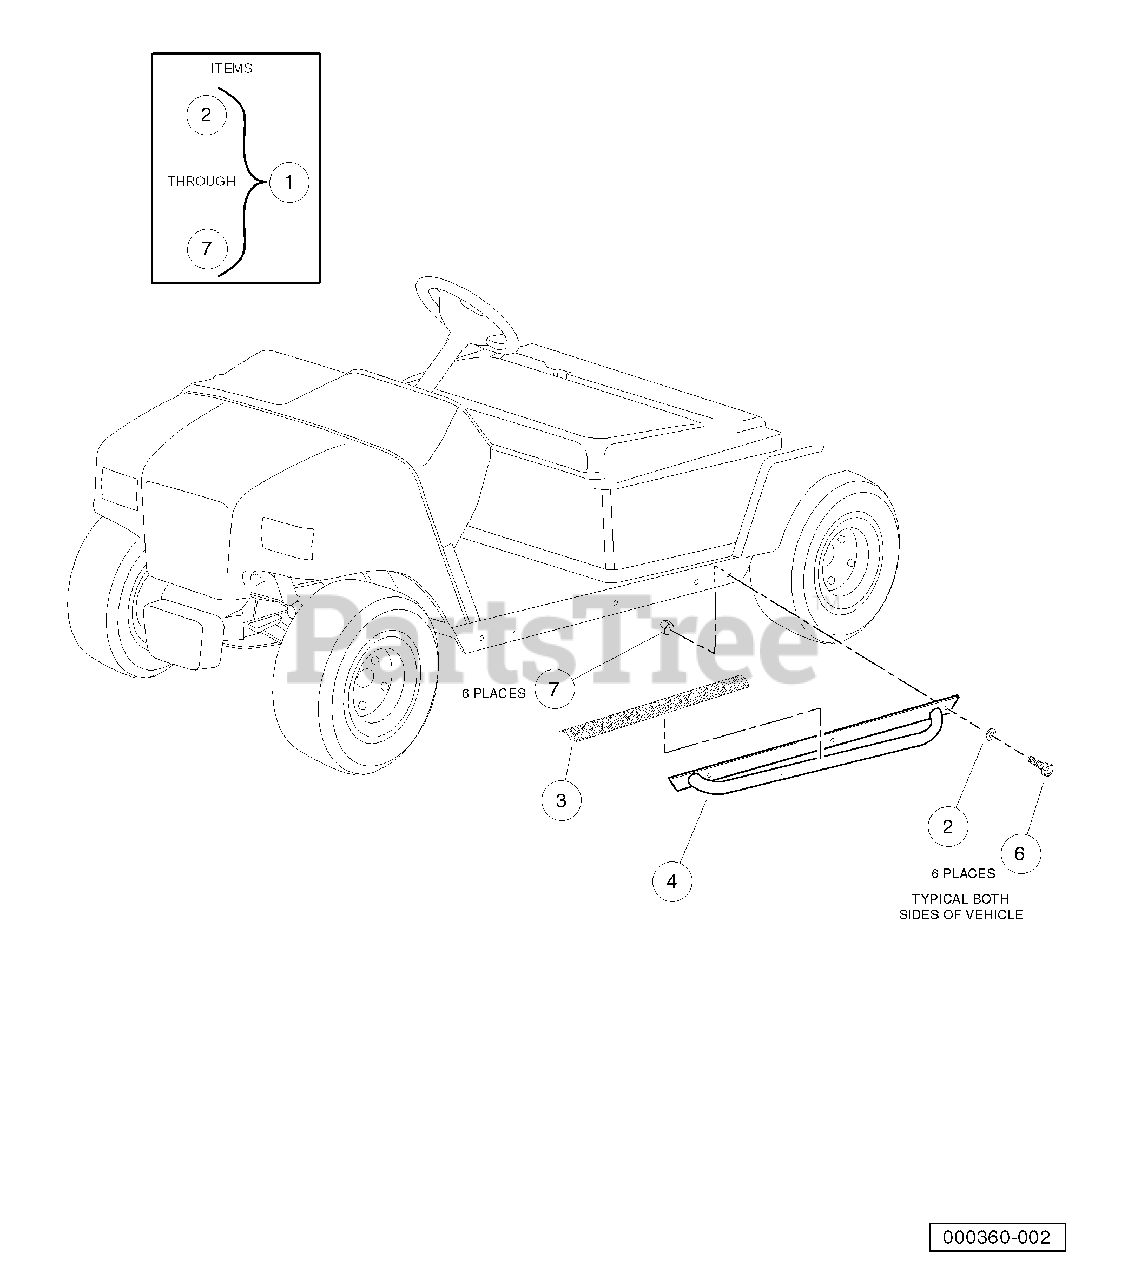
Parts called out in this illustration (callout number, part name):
1	Kit, Nerf Bar
2	Washer, 3/8 Flat
3	Tape, Non-skid
4	Nerf Bar Assy, Driver
5	Nerf Bar Assy, Passngr
6	Screw, 3/8-16 X 1.00 Hex-Head Cap
7	Locknut, 3/8-16 Hex
